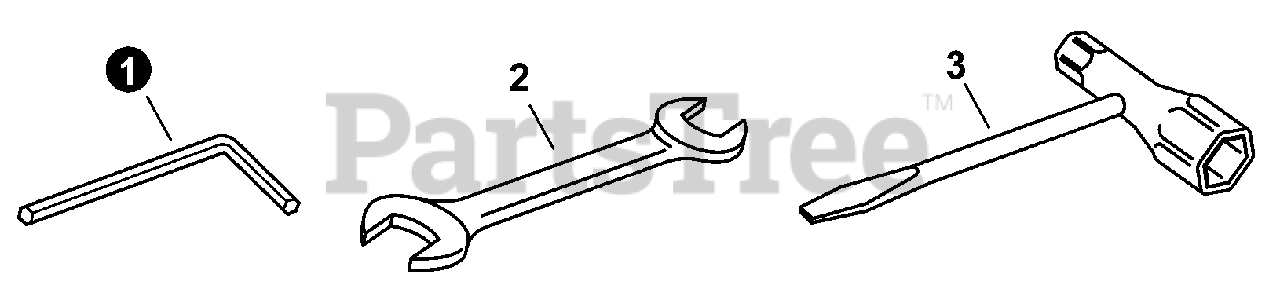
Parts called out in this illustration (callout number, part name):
1	WRENCH, ALLEN 4 MM
2	SPANNER 8x10
3	T-WRENCH 13x19x180
